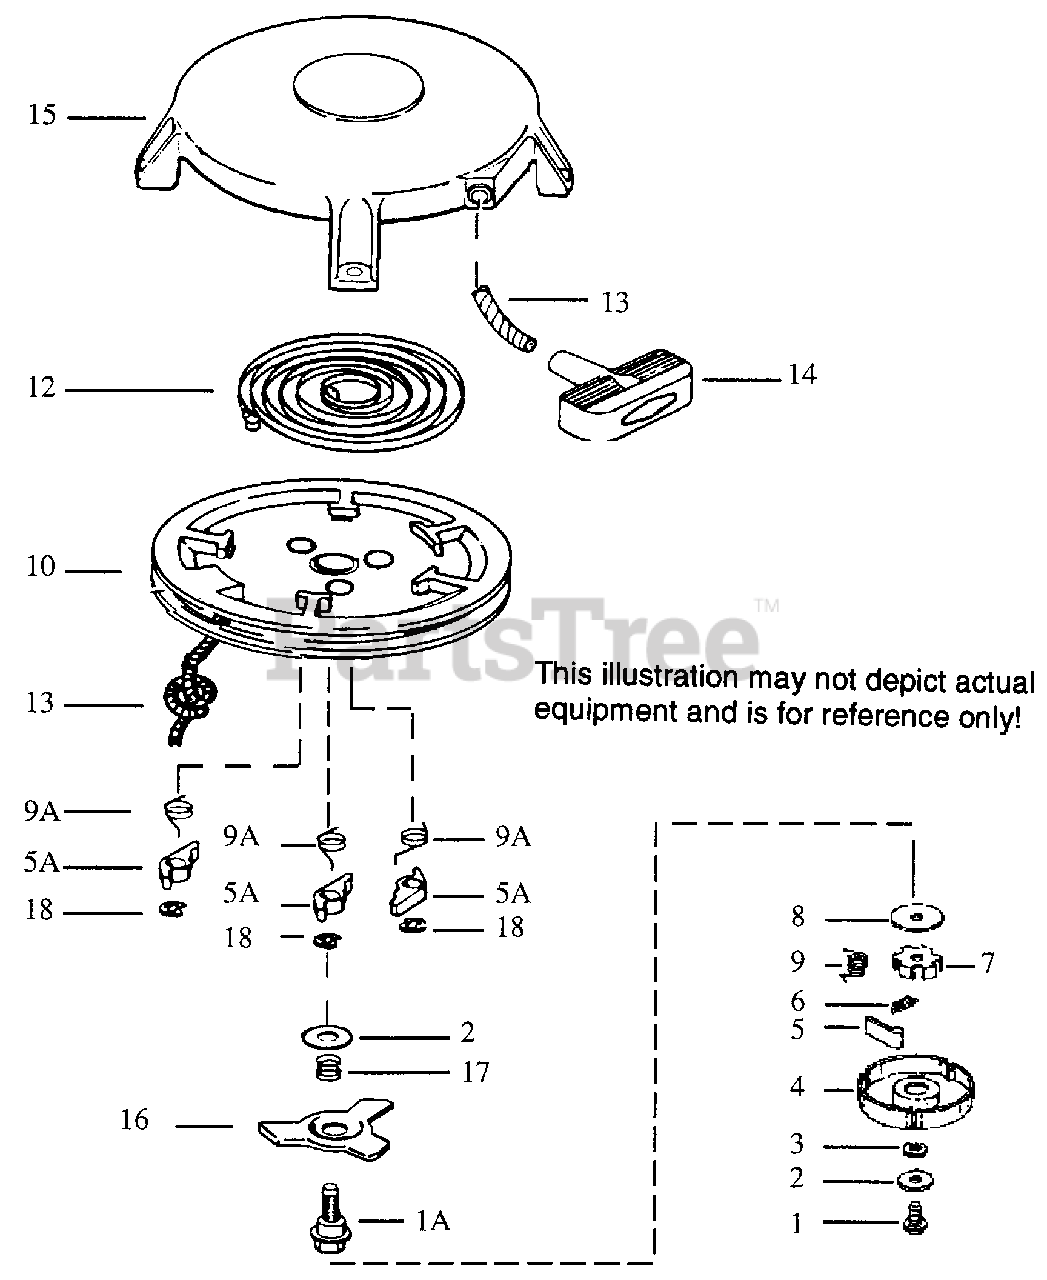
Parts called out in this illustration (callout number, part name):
1	Retainer Screw
2	Brake Washer
5	Stater Dog
6	Dog Cam
7	Brake Spring
8	Retainer Ring
9	Dog Spring
12	Rewind Spring
13	Starter Rope
14	Starter Handle Ass'y.
15	Starter Housing
